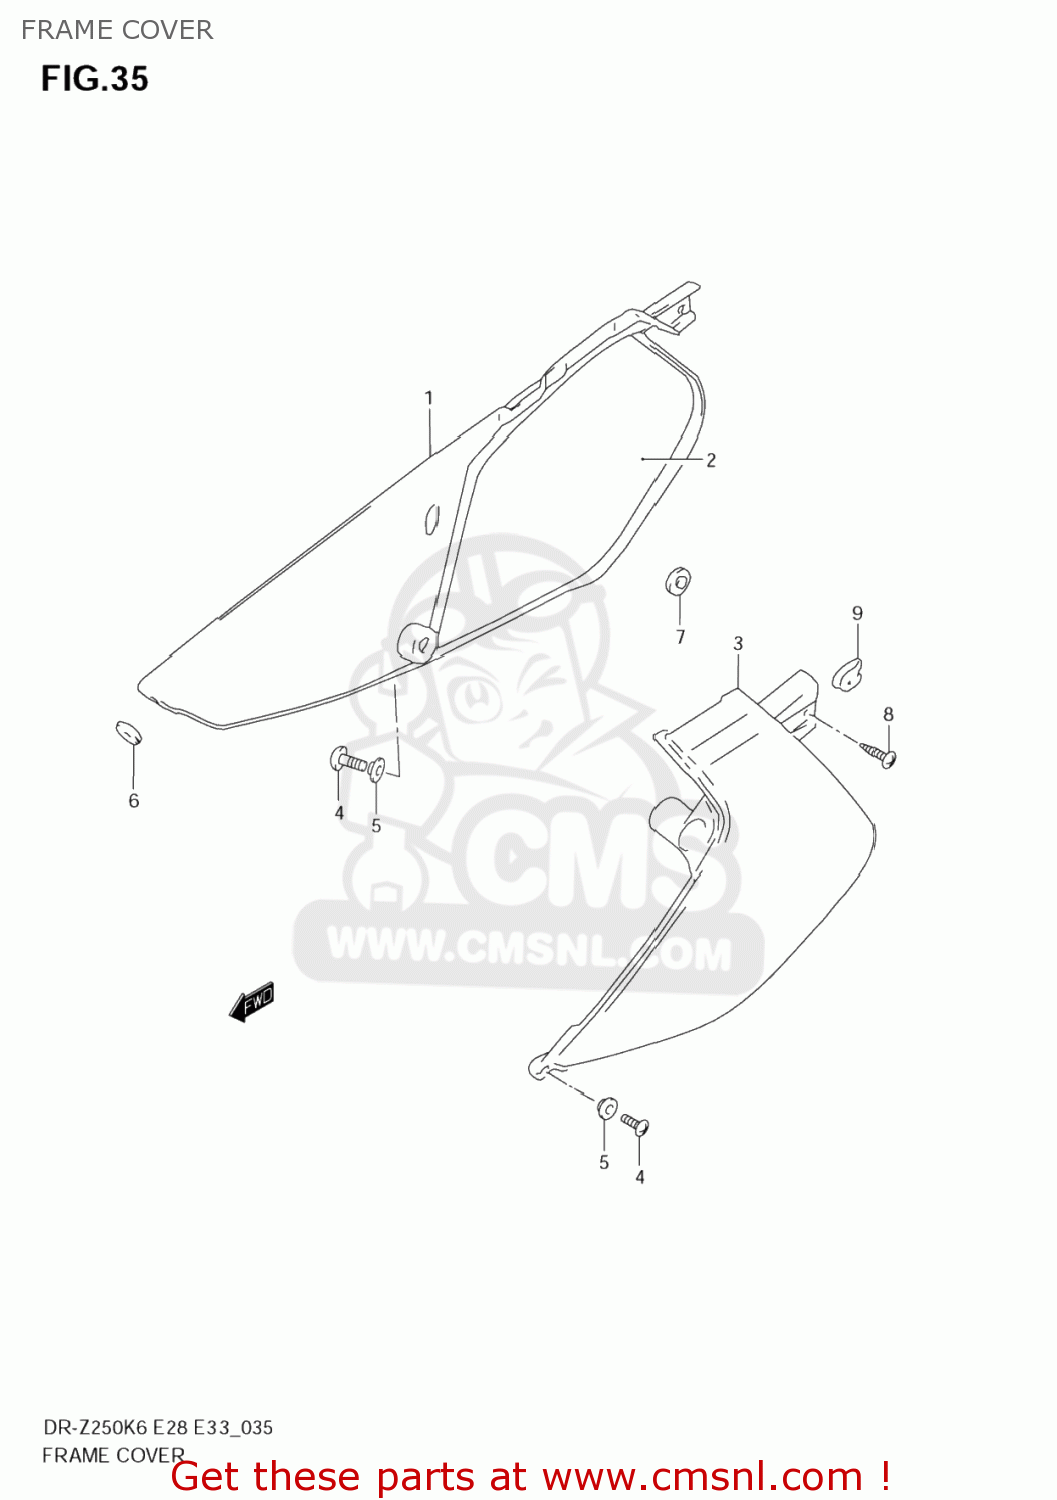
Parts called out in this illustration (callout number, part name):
1	COVER,FRAME,R(WHITE)
2	SHIELD,FRAME COVER,R
3	COVER,FRAME,L(WHITE)
4	SCREW 6X12
5	WASHER
6	CUSHION
7	CUSHION
8	SCREW
9	NUT
